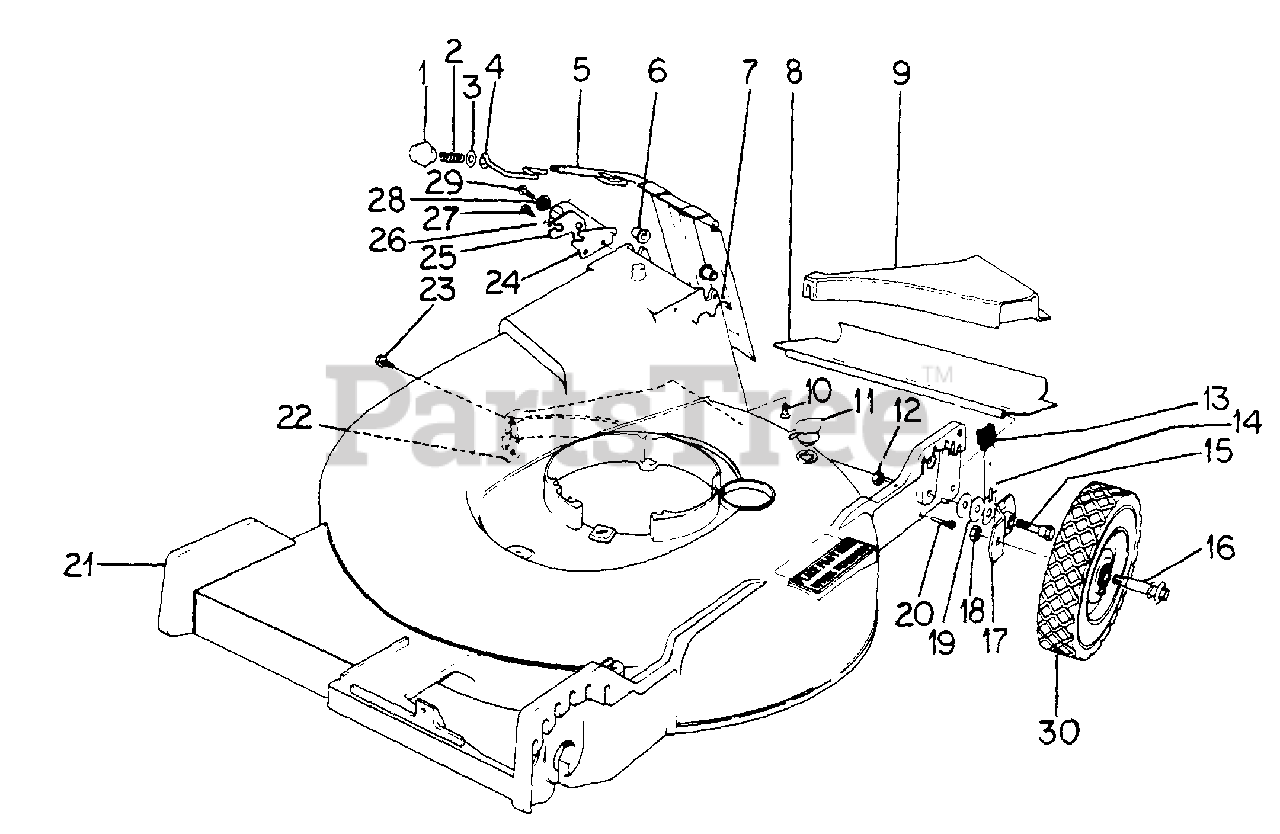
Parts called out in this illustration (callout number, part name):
1	KNOB, HANDLE
2	SPRING, COMPRESSION
4	LATCH, DOOR
5	HANDLE, DOOR
7	SPRING, DOOR
8	SHIELD, REAR
9	INSERT, REAR
11	PLUG, WASH-OUT
12	NUT, 5/16 CAD P/T LOCK TYPE
14	ARM, SPRING
15	BOLT, PIVOT
16	BOLT, WHEEL
17	PIVOT, LH REAR
17	PIVOT, RH REAR
19	WASHER, PIVOT
20	SCREW, PIVOT
21	HOUSING, MOWER
22	NUT, SPECIAL
23	SCREW, SELF TAPPING
24	CATCH, PLATE
26	SPRING, TORSION
27	SCREW, 1/4 X 1/2 H/HD TAP
28	WASHER, LATCH
30	WHEEL W/TIRE REAR
